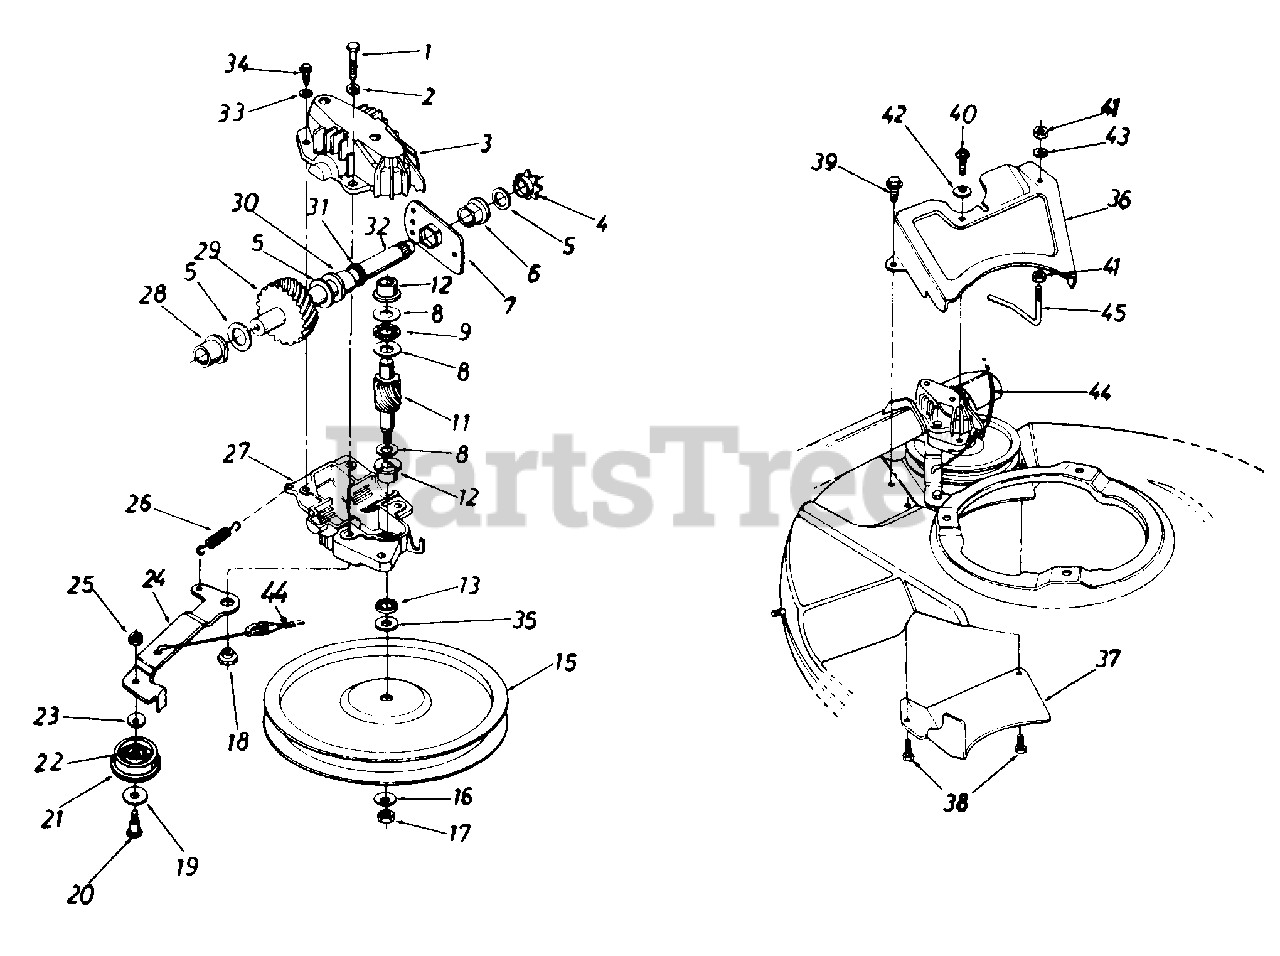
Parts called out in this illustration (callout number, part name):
1	Hex Bolt 1/4-20 x 1.25" Lg. w/ Patch
2	L-Wash. 1/4" I.D.
3	Upper Hsg. Half
4	#48 Sprocket 7 Tooth x 1/2 Pitch
5	Fl-Wash. 5/8" I.D. x .030
6	Hex Flange Brg. .631" I.D.
8	Thrust Wash. .382" I.D. x .70" O.D.
9	Thrust Bearing .375" I.D. x .812" O.D.
11	11 Tooth Helical Gear
12	Flange Bearing
13	Oil Seal
15	Fl-Pulley 5.06" I.D.
16	Bell-Wash. .265" I.D. x 75"
17	Hex Nut 1/4-28 L.H. Thd.
18	Shld. Spacer .375" Dia. x .170
19	Fl-Wash. .390" I.D. x 1.0"
20	Shld. Bolt .375" Dia. x .40"
21	Fl-Idler Plastic 1.50" Dia.
22	Needle Brg. .375" x .31"
23	Bell-Wash. .265" I.D. x 75"
24	Idler Brk't. Ass'y.
25	Hex Patch L-Nut 1/4-28 Thd
26	Extension Spring 1.12" Lg.
27	Lower Hsg. Half
28	Flange Bearing .56 Dia.
29	33 Tooth Helical Gear
30	Flange Bearing .629 Dia.
31	Oil Seal .625 Dia.
32	Gear Sprocket Shaft
33	L-Wash. #10 I.D.
34	Hex B-Tap Scr. #10 x .62"
35	Hex Washer .26" x .88"
39	Hex AB-Tap Scr. 1/4 x .50" Lg.
40	Hex B-Tap Scr. 1/4 x .62" Lg.
41	Hex Nut 1/4-20 Thd.
42	Bell-Wash. .265" I.D. x .75"
43	L-Wash. 1/4" I.D.
44	S.P. Cable-48" Lg.
45	S.P. Belt Guard
